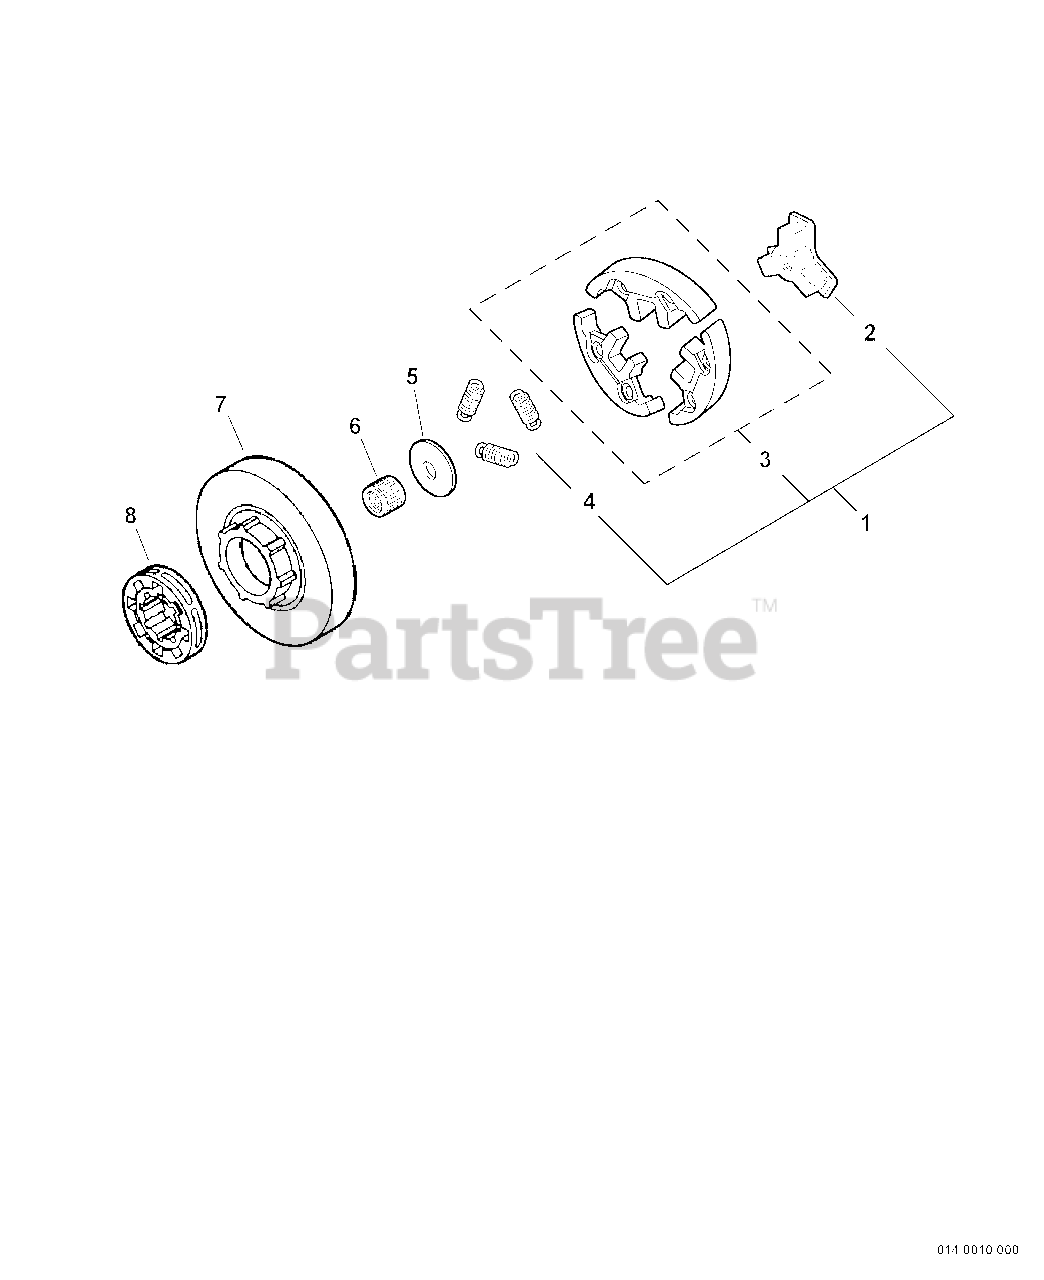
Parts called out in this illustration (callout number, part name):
1	CLUTCH ASSY
2	HUB, CLUTCH
3	CLUTCH SHOE SET
4	SPRING, CLUTCH
5	PLATE, CLUTCH
6	BEARING, NEEDLE
7	DRUM, CLUTCH
8	SPROCKET, RIM
